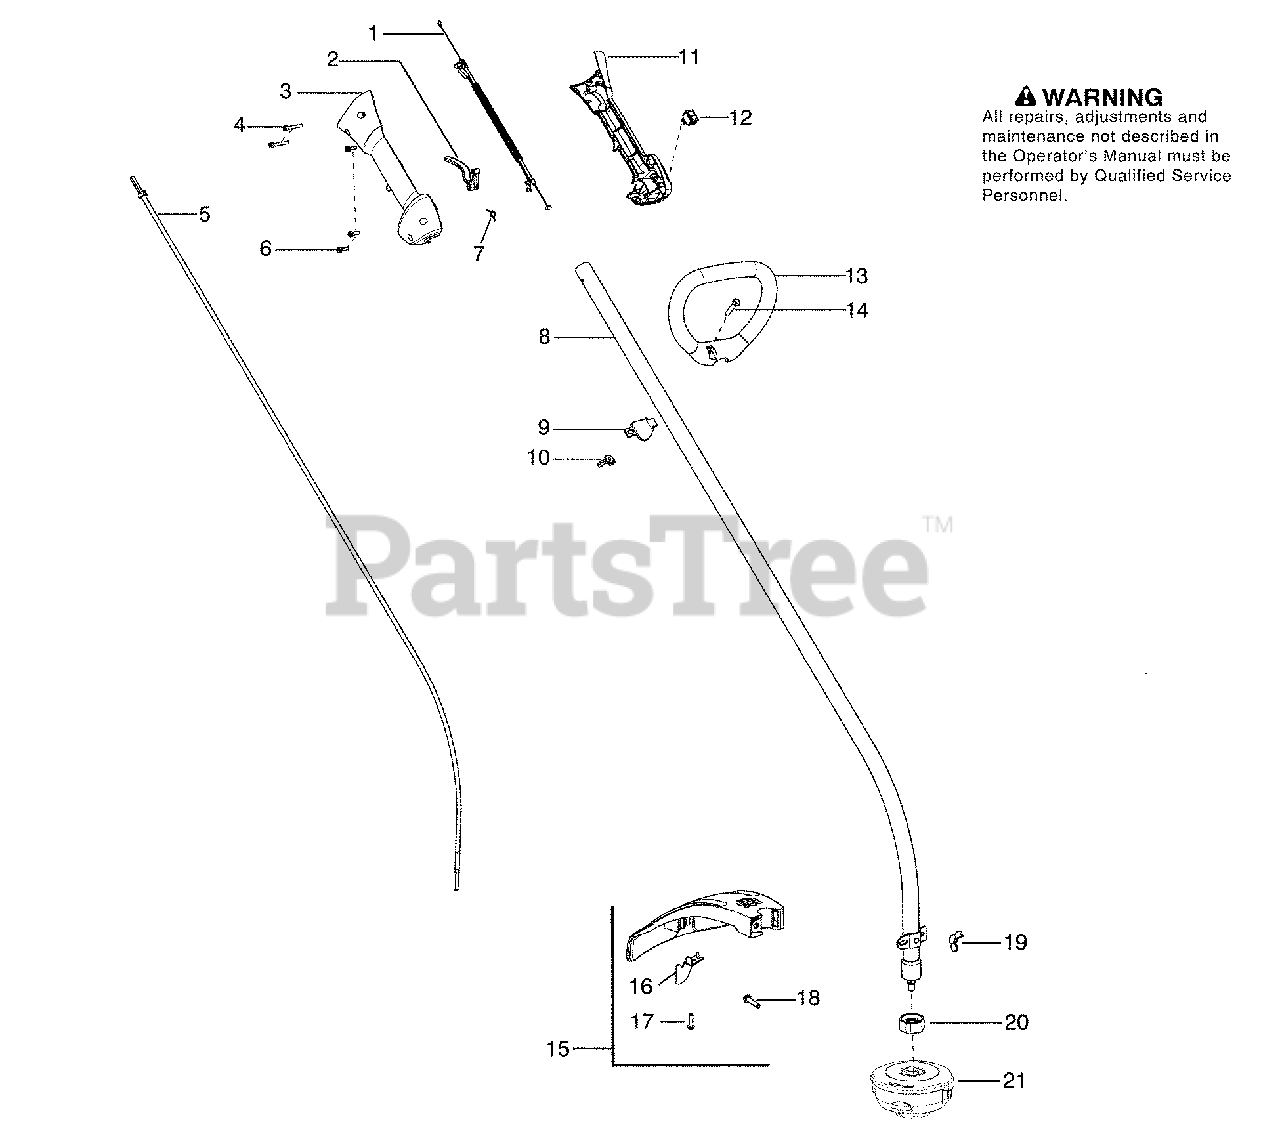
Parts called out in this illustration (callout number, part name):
1	Assy-Cable/Wire Harness
3	Housing-Throttle (RH)
5	Flexshaft
7	Spring-Trigger
8	Kit-Driveshaft
9	Clamp-Handle
10	Wingnut
11	Housing-Throttle (LH)
12	Kit-Switch
13	Handle-Assist
15	Kit-Shield
16	Kit - Limiter-Line
19	Wingnut
21	Assy-T25 Cutting Head
